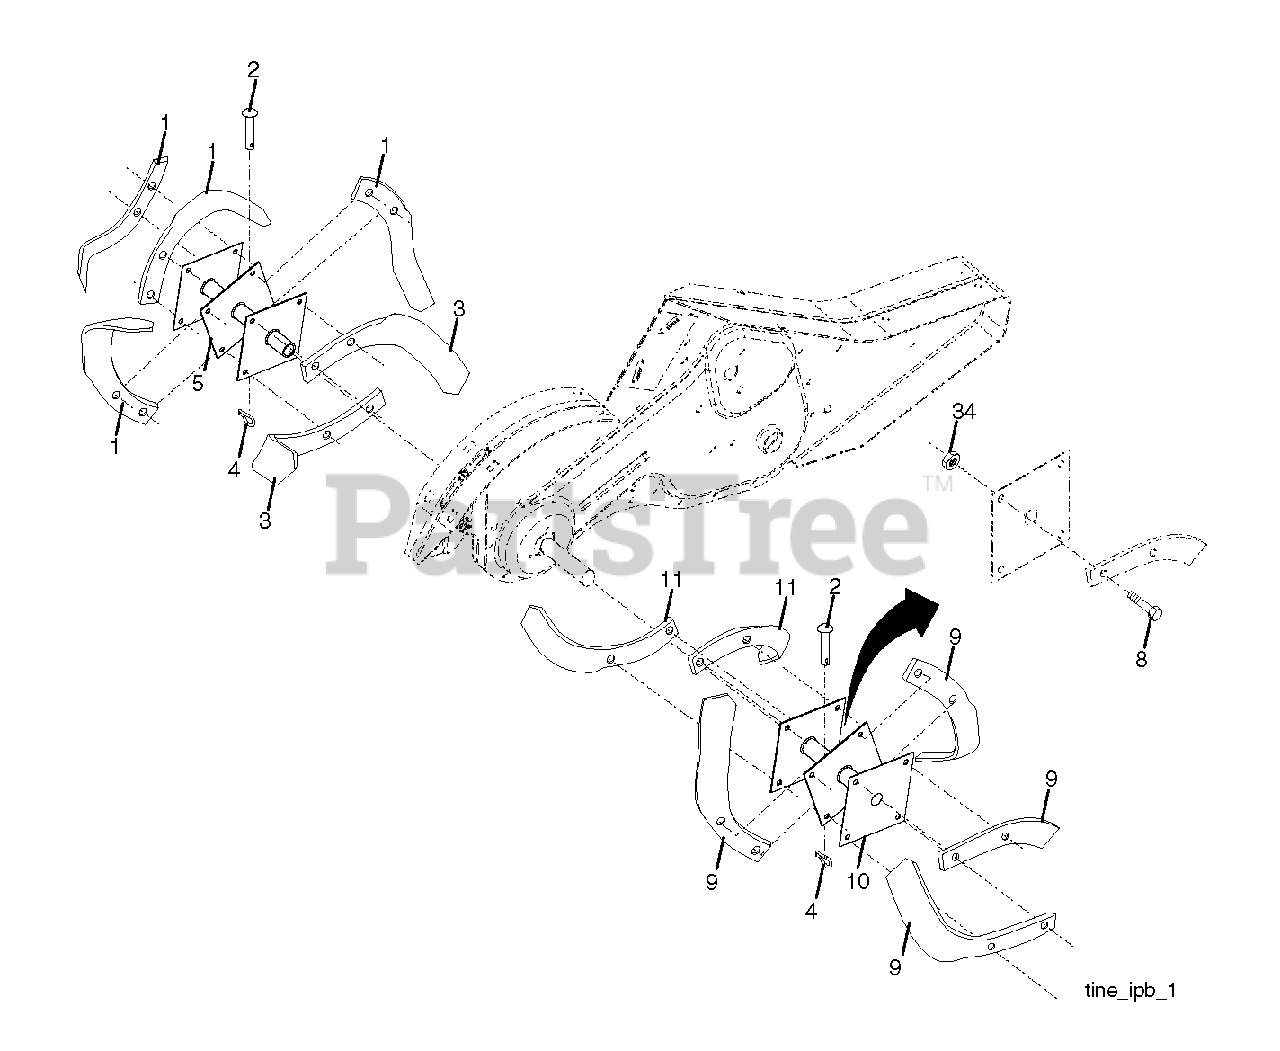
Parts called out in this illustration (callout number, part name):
1	TINE TI
4	SPRING RETAINER
5	HUB & PLATE ASM LH
8	BOLT.HEX.001X20.37-24X1.ZINC
9	TINE TI
10	HUB & PLATE ASM RH
11	TINE.RH.12"(72R)
34	NUT CROWNLOCK 3/8-24
